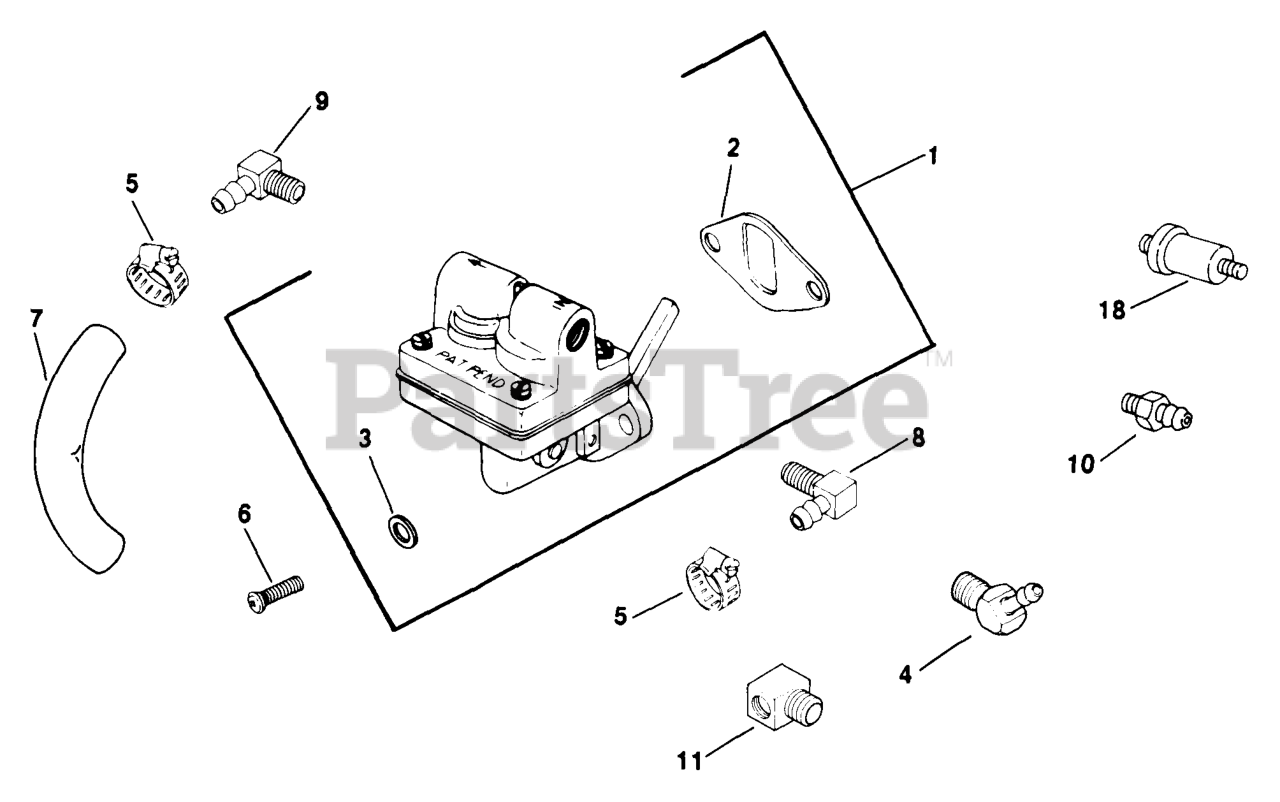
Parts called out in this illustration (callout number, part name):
2	GASKET - USE 25 041 09
3	WASHER, FLAT 1/4" (O.D. 1/2")
4	CONNECTOR, 45 DEG.
5	CLAMP, HOSE 1/2" USE 25 237 14-S
6	SCREW, SEMS 1/4-20X3/4"
7	LINE - DISCONTINUED
8	CONNECTOR, 90 DEG. HOSE
9	CONNECTOR, 90 DEG. - DISCONTINUED
